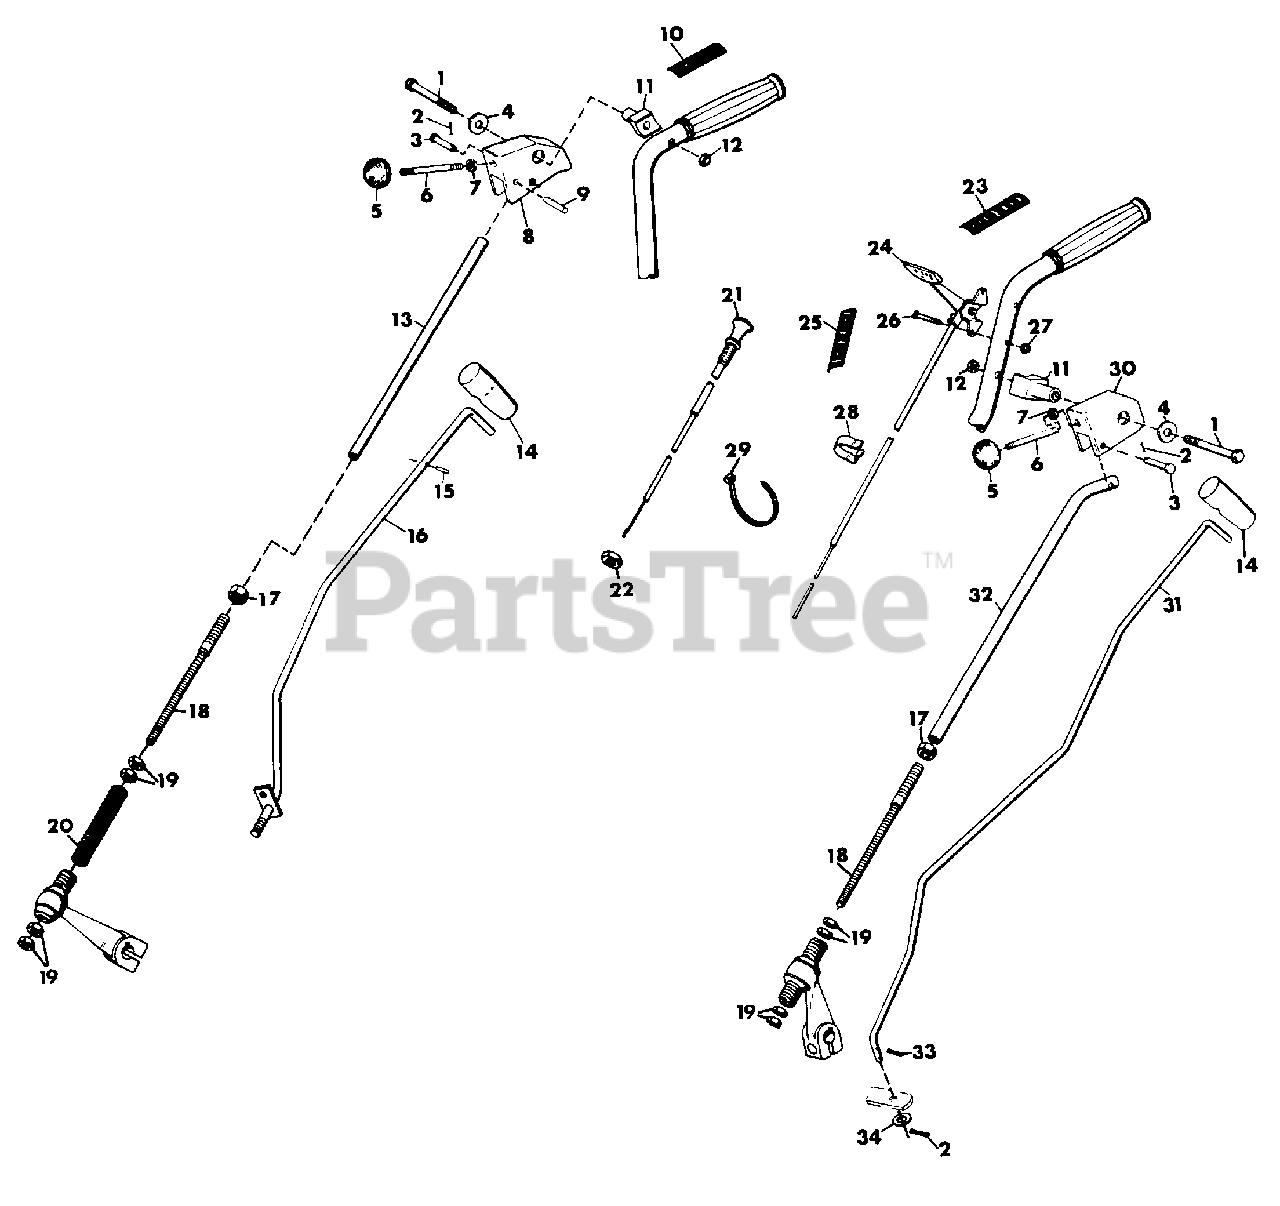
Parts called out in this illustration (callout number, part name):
1	BOLT, HEX 1/2-13X3.50
2	PIN, COTTER .125X.750
3	PIN, CLEVIS .375X1.250
4	WASHER, FLAT .531X1.062X.095
5	KNOB, CONTROL
6	ROD, SHIFTER
7	NUT, JAM 7/16-20 HEX
8	SUPPORT, FWD-REV SHIFTER ROD
9	PIN, SPRING .25X1.125
10	DECAL, FWD-REV
11	PIVOT, HANDLE LEVER
12	NUT, LOCK 1/2-13 E.T.
13	ROD, FWD-REV CONTROL
14	HANDLE, RUBBER SHIFTER(MODEL 5200)
14	HANDLE, RUBBER SHIFTER(MODELS 5240,5260,5665,5645)
15	PIN, SPRING .094X.688(MODELS 5240, 5260,5465, 5665 AND 5645)
16	WELDMENT, 2-SPEED CONTROL ROD(MODELS 5240,5260,5465, 5665 AND 5645)
17	NUT, JAM 1/2-13
18	ROD, CONTROL EXTENSION
19	JAM, HEX 3/8-16
20	SPRING, FWD-REV NEUTRAL RETURN
21	CONTROL, CHOKE(MODELS 5260, 5465 AND 5665)
22	NUT, JAM 3/8-24 HEX(MODELS 5260, 5465 AND5665)
23	DECAL, THROTTLE
24	LEVER, THROTTLE CONTROL 8 H.P.
24	LEVER, THROTTLE CONTROL10 H.P., 12 H.P., 16 H.P.
25	DECAL, GEAR SHIFT
26	SCREW, MACH. 10-24X1.50 PAN HD
27	NUT, LOCK 10-24
28	CLIP, CONDUIT
29	TIE, CABLE
30	SUPPORT, HI-LO SHIFTER ROD
31	ROD, ATTACHMENT THROW-OUT
32	ROD, HI-LO CONTROL
33	PIN, COTTER .094X1.000
34	WASHER, FLAT .406X.812X.065
